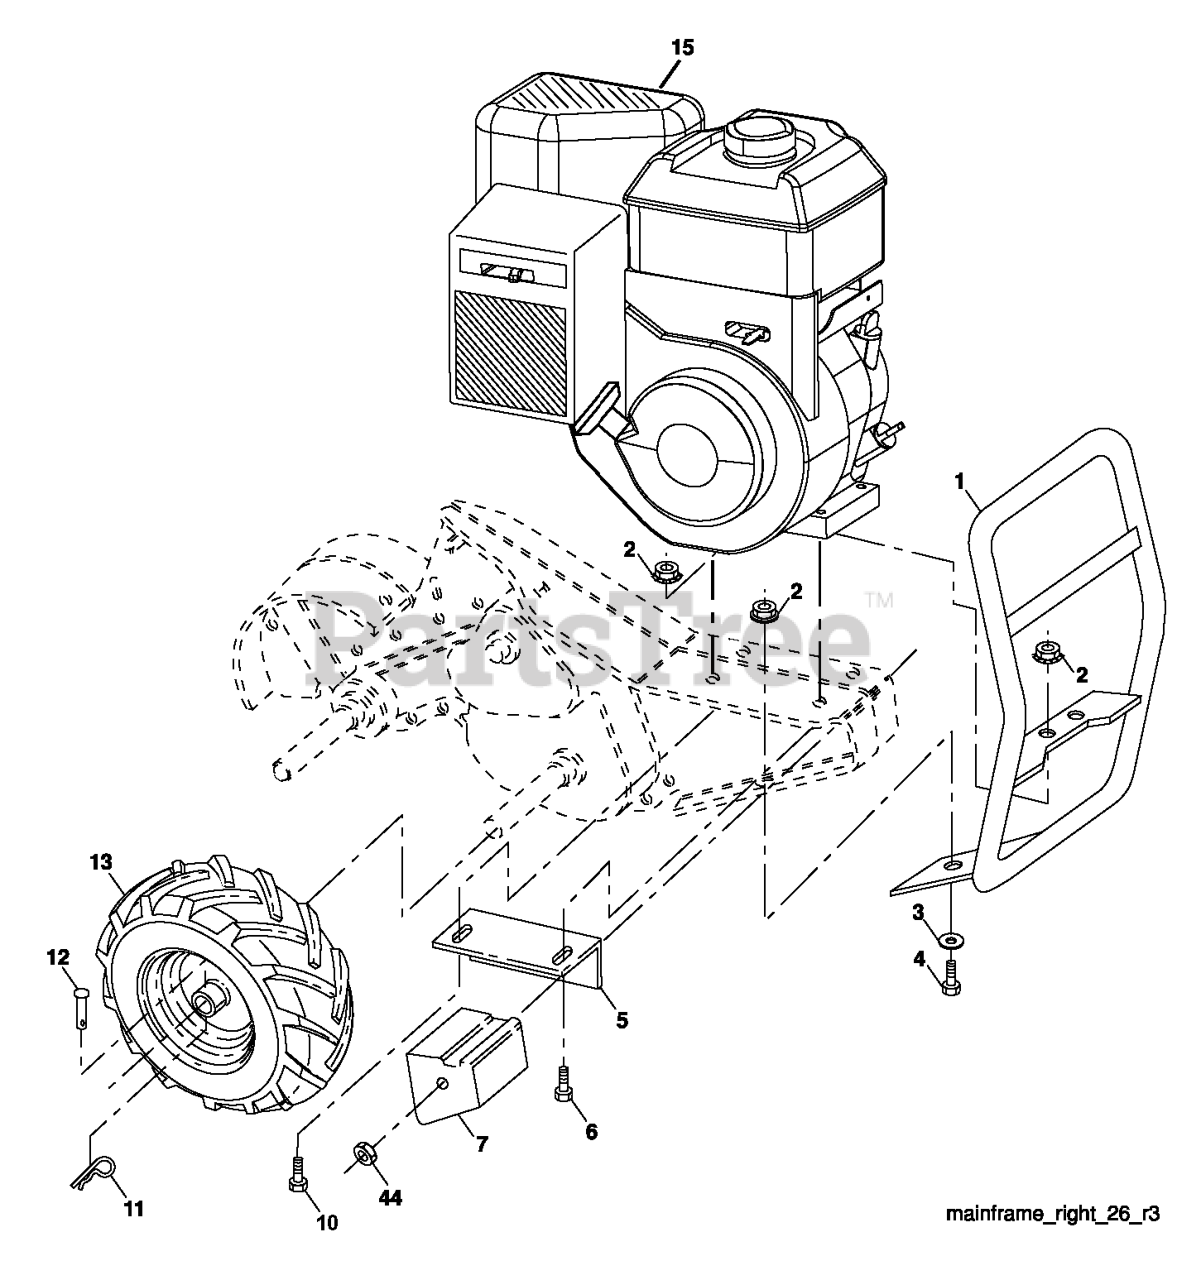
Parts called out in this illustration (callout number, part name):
1	BUMPER.ASM.REAR.TILLER.479
2	LOCKNUT-FLANGE 5/16-18
3	WASHER
4	BOLT
5	BRACKET.REINFORCEMENT.RH.BLACK
6	BOLT, HEX 5/16-18X1-3/4
7	COUNTERWEIGHT, RH
10	BOLT
11	RETAINER M
12	RIVET,DRILLED
13	WHEEL.DRT.RH.13X5X6.SILVER.KEN
